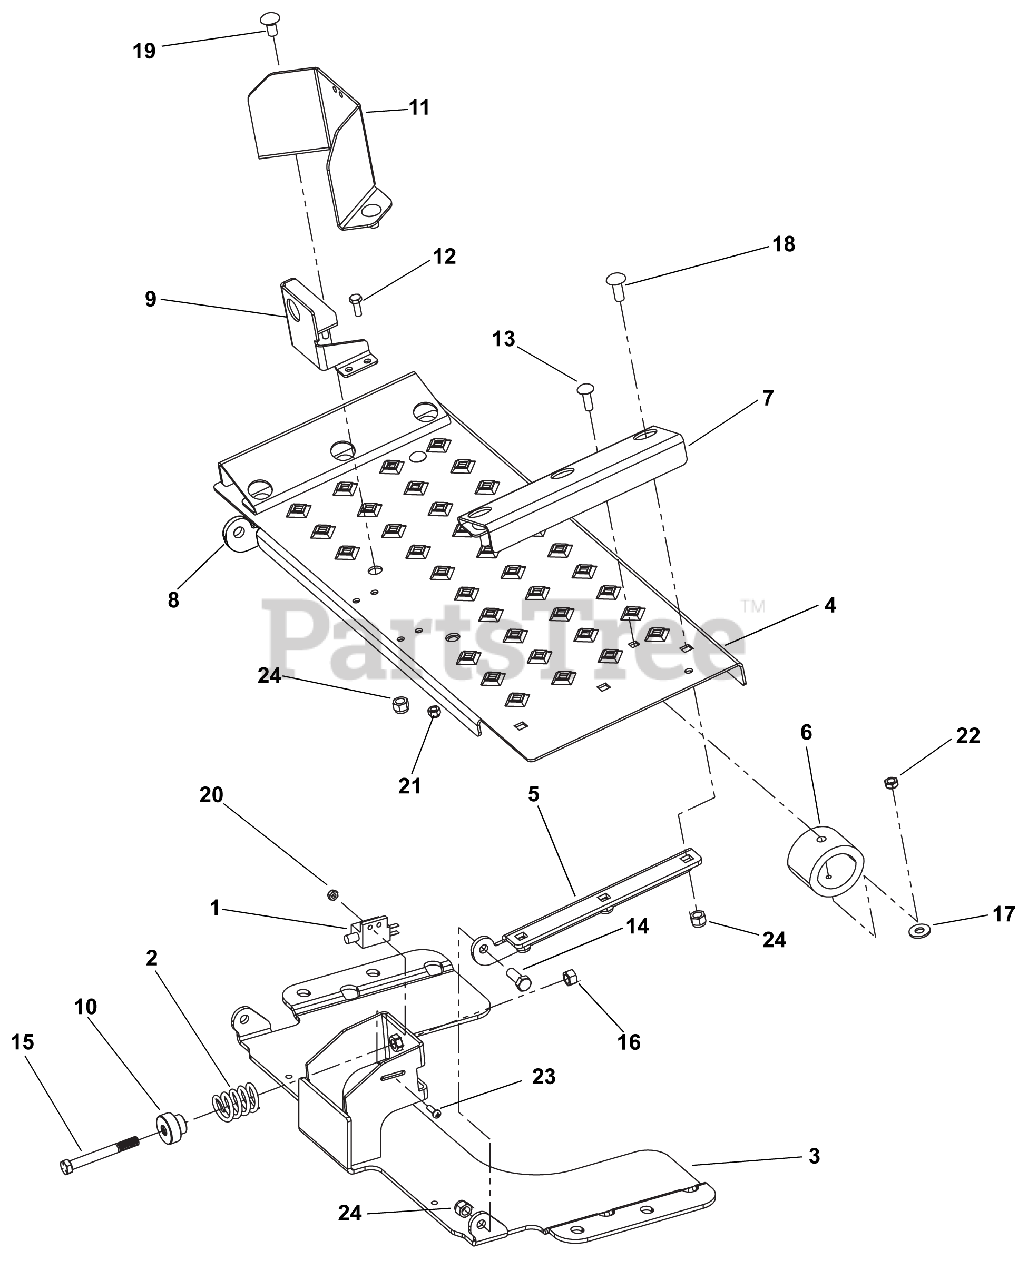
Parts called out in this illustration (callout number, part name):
1	SWITCH
2	SPRING
3	WLDMT, PLATFORM
4	PLATE, PLATFORM
5	PLATE, PLATFORM TAB
6	BUMPER, MINER GBR-6
7	WEDGE, PLATFORM
8	PLATE, PLATFORM TAB LH
9	ANCHOR, OPC
10	WASHER, SPRING Y
11	COVER, OPC
12	BLT-HEX M12 X 1.75X25 YWZC
13	@BLT-RDHDSQNK .31-18X1.00 G5YZ
14	BOLT,JDS19-.375-16UNC (960046)
15	@BLT-HEX .38-16X3.25 GR5 YWZC
16	@NUT-HEX .31-18 YWZC
17	@WSHR-FL-STL.38X.875X.083 YWZC
18	@BLT-RDHDSHSQNK.38-16X1.0 G5YZ
19	@BLT-RDHDSQNK .38-16X.75 G5YZ
20	NUT-LK-JAM-CTR .375-16 PL
21	@NUT-LK-NYL .250-20 YWZC
22	@NUT-LK-NYL .312-18 YWZC
23	SCR-MCH 10-24X.62 P/HD
24	@NUT-LK-NYL .38-16 YWZC
